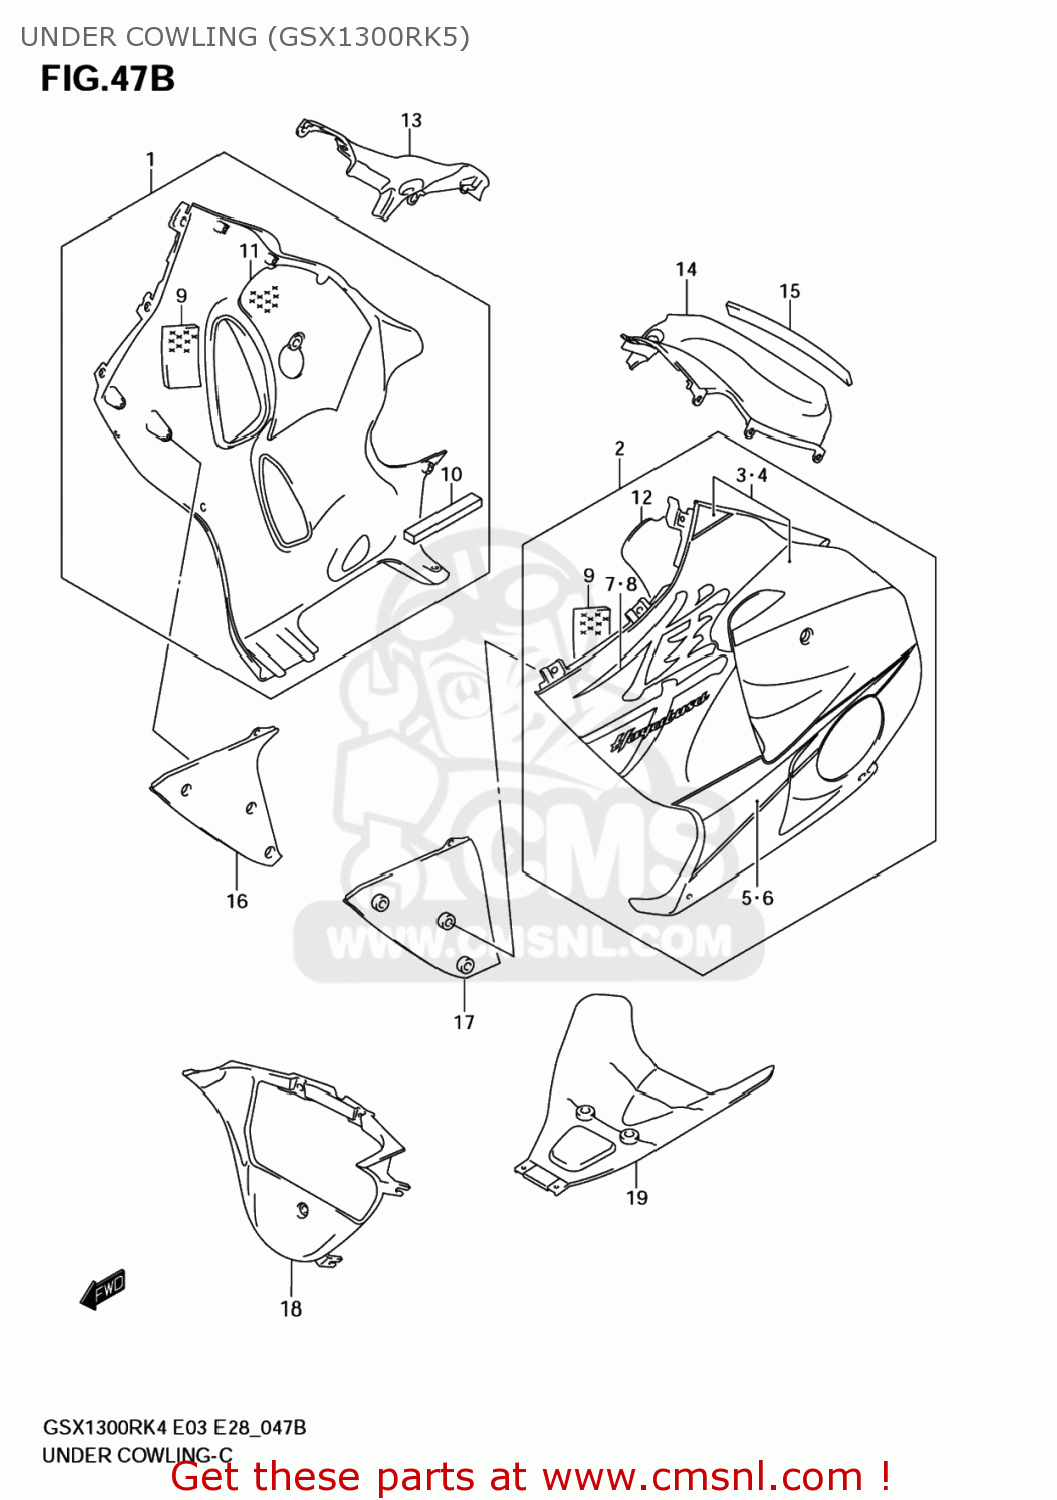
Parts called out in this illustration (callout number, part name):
1	COWL ASSY,UNDE
2	COWL ASSY,UNDE
3	TAPE SET,UNDER COWLING UPR,R
4	TAPE SET,UNDER COWLING UPR,L
5	TAPE, LOWER RH
6	TAPE,UNDER COW
7	EMBLEM,COWLING UNDER,R
8	EMBLEM,COWLING UNDER,L
9	CUSHION,UNDER COWLING NO,1
10	CUSHION,ENGINE COVER,RIGHT
11	CUSHION,UNDER COWLING NO.2,R
12	CUSHION,UNDER COWLING,L
13	PANEL,SIDE,R
14	PANEL,SIDE,L
15	MOLDING,SIDE PANEL
16	COWLING,UNDER INNER,R
17	COWLING,UNDER INNER,L
18	COWLING,UNDER CTR
19	COWLING,UNDER RR
